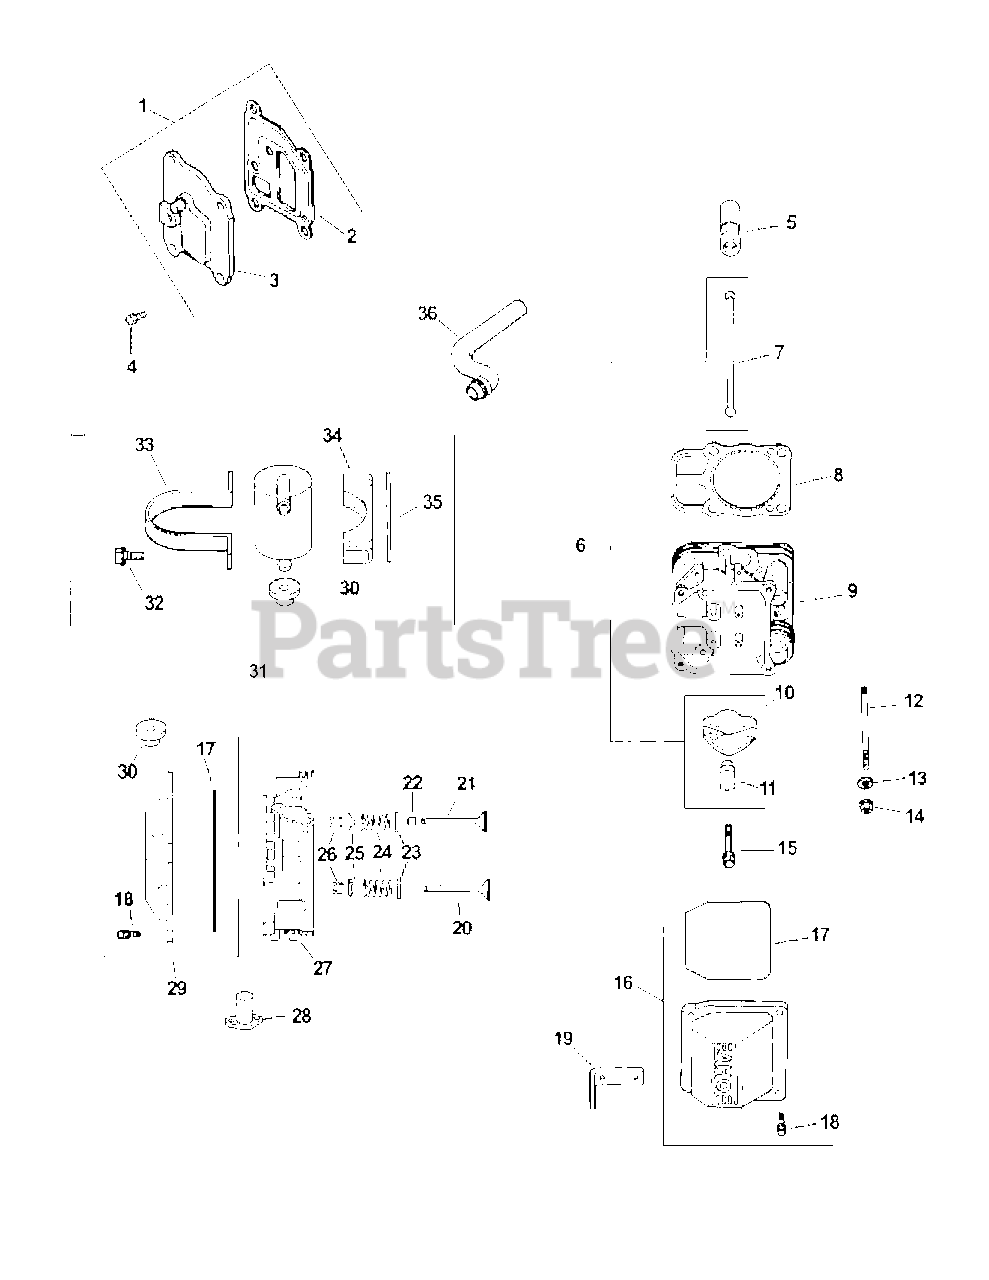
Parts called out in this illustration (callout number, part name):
1	Breather Cover Kit
2	Breather Gasket
3	Breather Cover
4	Hex Flange Screw
5	Valve Lifter
6	Valve Train Kit
9	Head Assembly #2 Cylinder
11	Rocker Arm Pivot
12	Cylinder Head Stud
13	Flat Washer 1/4
14	Hex Flange Nut
15	Hex Flange Screw
16	Valve Cover Kit, Plain
18	Hex Flange Screw
19	Lifting Strap
20	Exhaust Valve (Std.)
20	Exhaust Valve (.25)
21	Intake Valve (Std.)
21	Intake Valve (.25)
22	Valve Stem Seal
23	Spring Retainer
24	Valve Spring
25	Valve Spring Cap
26	Retainer Kit
27	Head Assembly #1 Cylinder
28	Exhaust Port Liner
29	Valve Cover Kit, Breather
30	Rubber Grommet
31	Breather Separator Kit
32	Hex Flange Screw
33	Breather Strap
34	Breather Separator Bracket
36	Breather Hose
